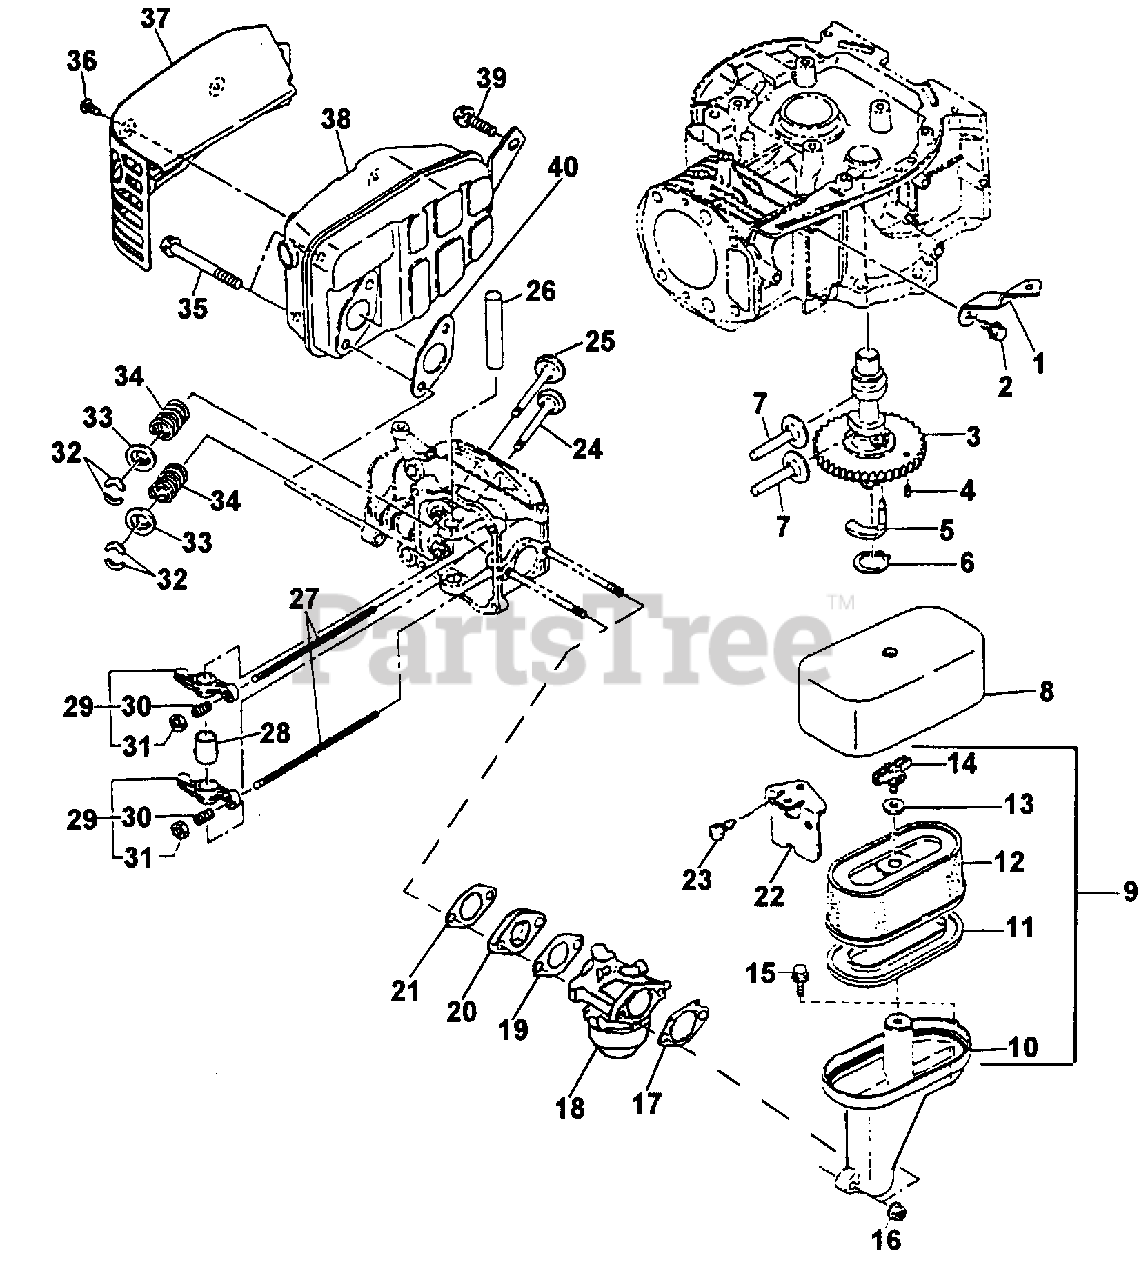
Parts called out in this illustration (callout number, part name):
1	BRACKET, Air Cleaner
2	BOLT, Flange
4	PIN, Spring
5	LEVER, Release
6	RING, Snap
8	COVER, Air Cleaner
9	AIR CLEANER
10	BASE, AIR CLEANER
12	ELEMENT SET
14	BOLT, Wing
15	BOLT, Flange
16	NUT, Flange
18	CARBURETOR
19	GASKET, Insulator
20	INSULATOR
21	GASKET, Insulator
22	BRACKET, Air Cleaner Cover
23	BOLT, Tapping
24	VALVE, Exhaust
25	VALVE, Intake
26	SHAFT, Rocker
27	ROD, Push
29	ROCKER ARM
30	SCREW, Adjusting
32	KEEPERS, VALVE
33	RETAINER
34	SPRING, Valve
35	BOLT AND WASHER
36	SCREW, Tapping
37	COVER, Muffler
39	BOLT AND WASHER
40	GASKET, Exhaust
